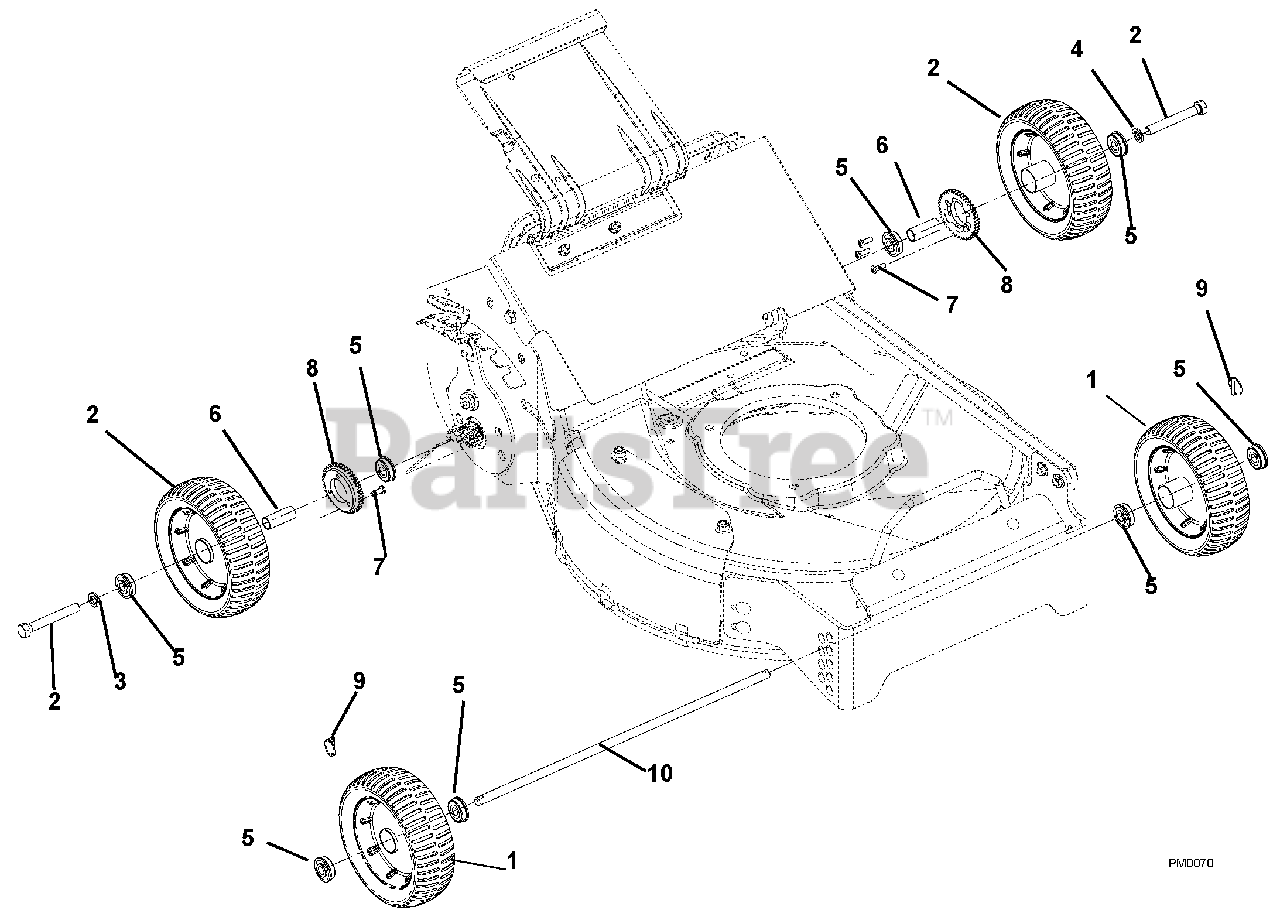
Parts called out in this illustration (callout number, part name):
1	WHEEL ASSY,8.25X2.75 FRONT
2	WHEEL ASSY,8.25X2.75 REAR
3	@BLT-HEX .50-13X3.75 GR5 YWZC
4	@WSHR-LK .50X.125 REG YWZC
5	BRG-BALL .500X1.38X.437
6	SPACER,WHEEL
7	SCR-TAP 1/4-20X3/4 LPAN TL BZ
8	GEAR, WHEEL
9	PIN-KLIK 1.000X.188X1.25 YWZC
10	AXLE SHAFT
